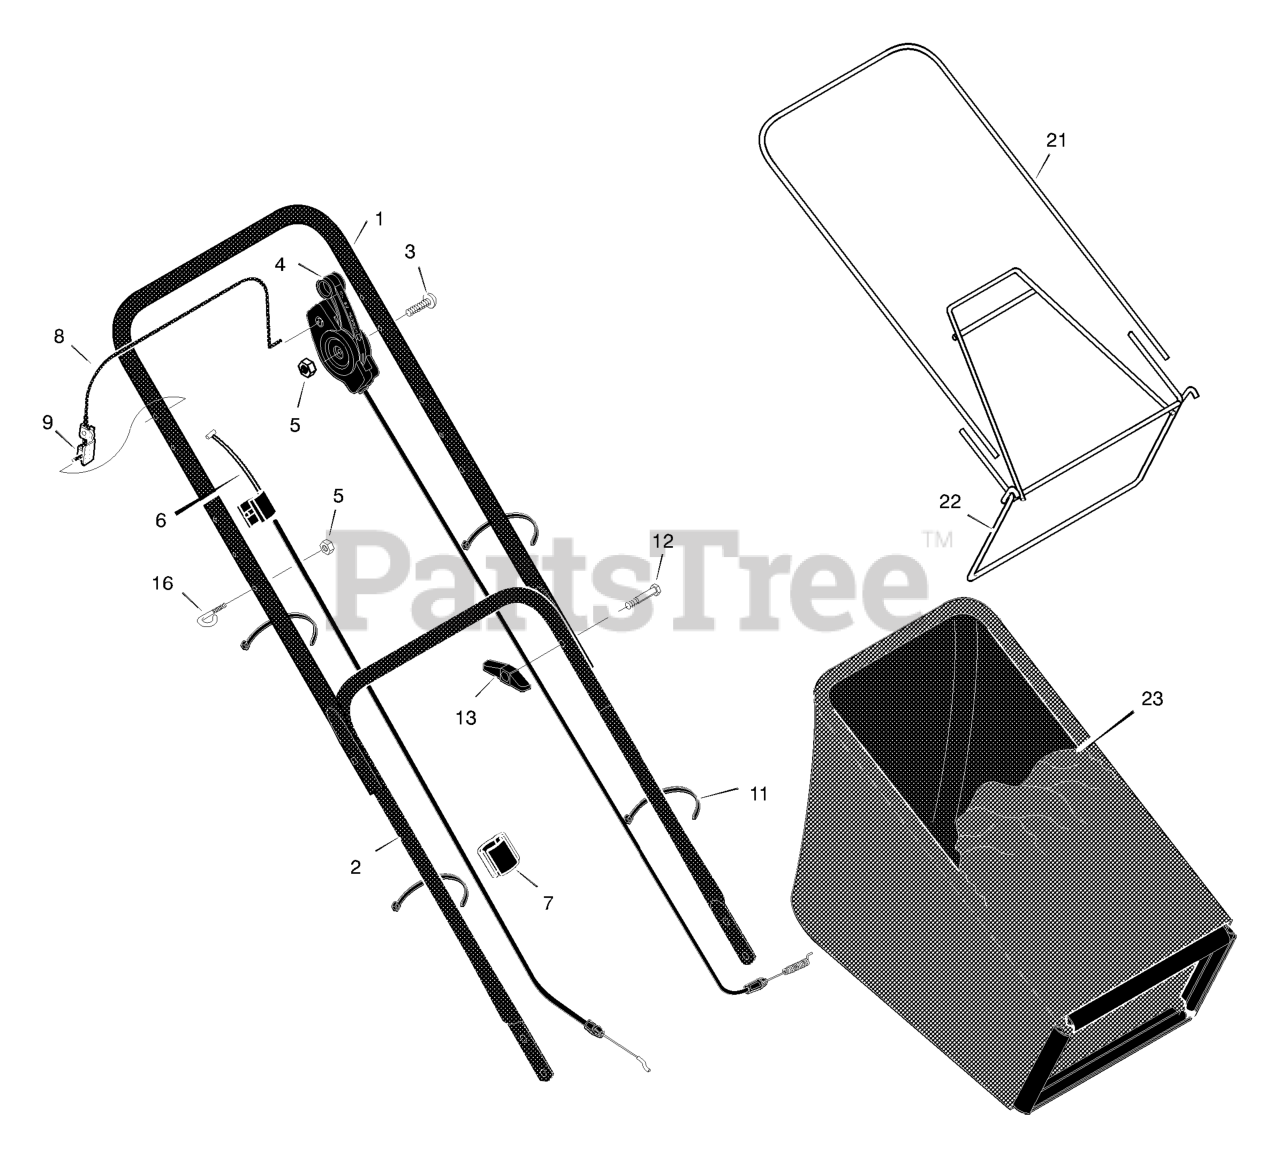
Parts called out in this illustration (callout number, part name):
1	Handle, Upper (Black)
2	Handle, Lower (Black)
4	Control, Drive
5	Locknut
6	Cable, Stop
7	Fastener, Single Cable
8	Lever, Stop
9	Bracket, Stop Lever
11	Fastener, Cable
13	Knob
16	Guide, Rope
21	Frame, Top
22	Frame Assembly
23	Bag, Cloth
